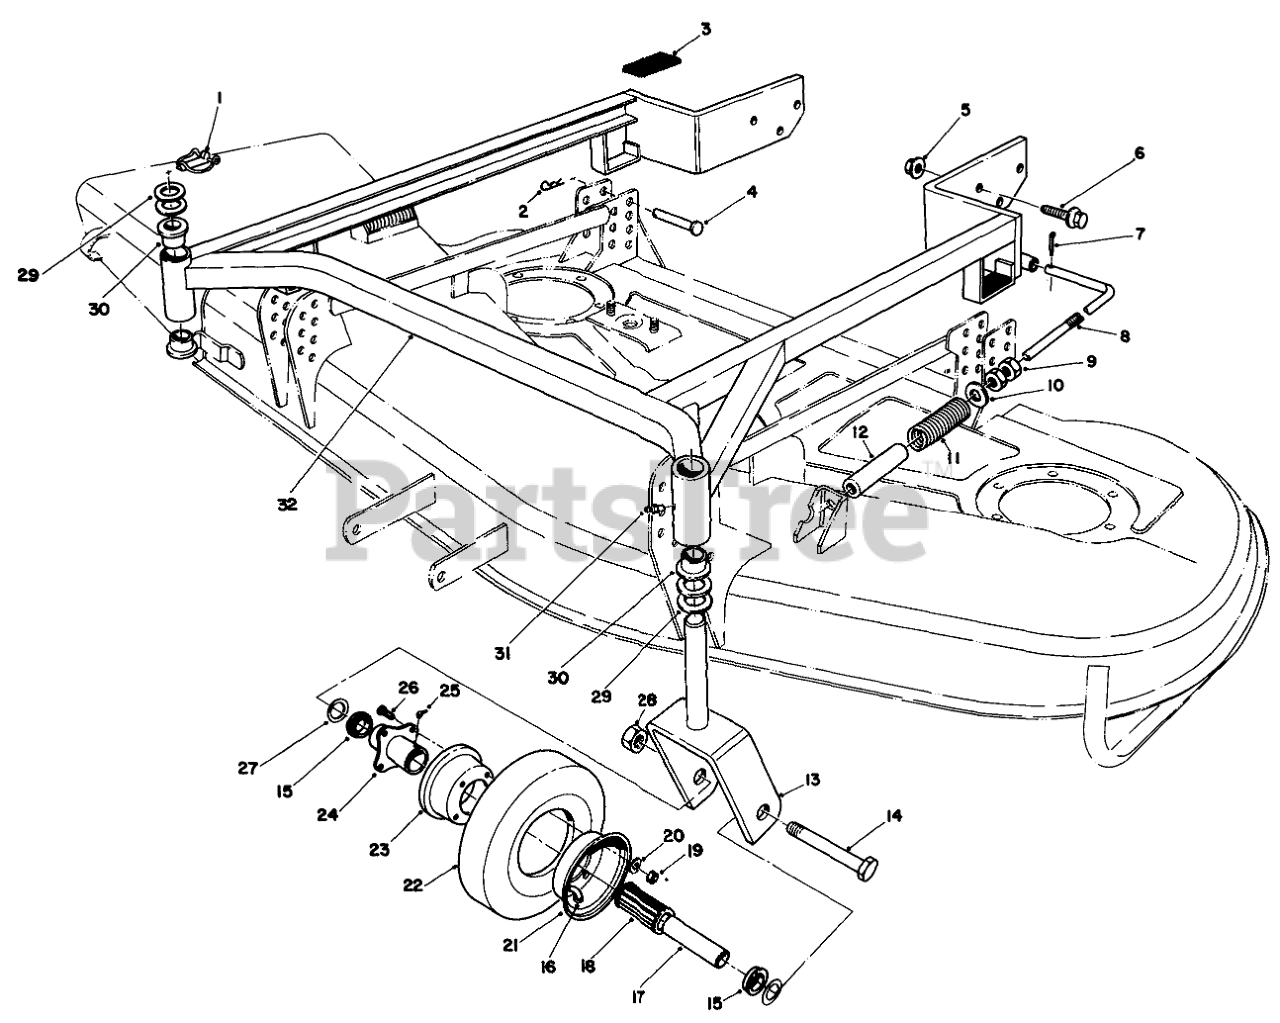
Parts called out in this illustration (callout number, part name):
1	PIN-LYNCH
2	PIN-HAIR
3	Cushion-Rubber
4	PIN-CLEVIS
5	NUT-LOCK, FLANGE
6	SCREW-HHF
7	PIN-COTTER
8	ADJUSTING SHAFT
9	NUT-JAM
10	WASHER
11	SPRING-COMPRESSION
12	SLEEVE-TUBE, 36 INCH
13	FORK-Castor
14	SCREW-HH
15	RETAINER
17	Bushing-Spanner
18	BEARING-ROLLER
19	NUT-HEX
20	WASHER-LOCK
21	WHEEL HALF-MALE
22	TIRE-8 Inch (4-PLY)
23	WHEEL HALF-FEMALE
24	HUB-CENTERED
25	FITTING-GREASE
26	WHEEL BOLT
27	SPACER-WHEEL
28	NUT-LOCK
29	WASHER-THRUST
30	Bushing
31	FITTING-GREASE
32	Frame-Carrier (Incl. Ref. #30)
